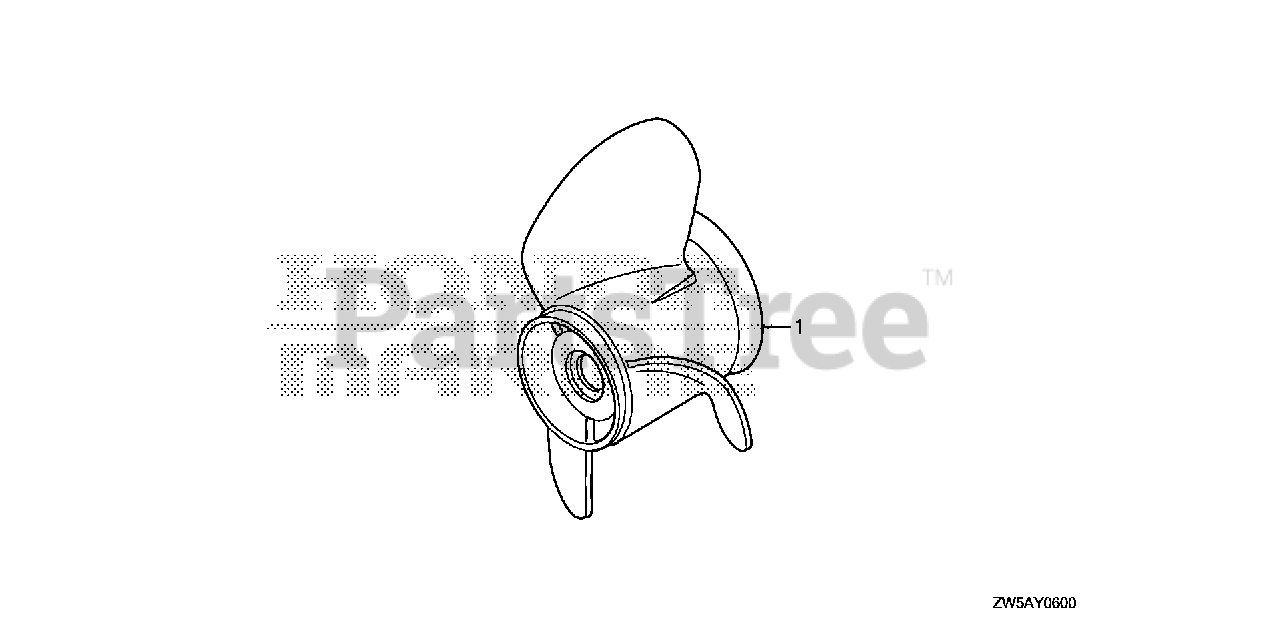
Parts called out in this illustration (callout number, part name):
1	PROPELLER, THREE-BLADE (13X19) (SUS)
1	PROPELLER, THREE-BLADE (13X21) (SUS)
1	PROPELLER, THREE-BLADE (14X11) *NH283* (AL) (STIN GRAY)
1	PROPELLER, THREE-BLADE (13-3/4X13) *NH283* (AL) (STIN GRAY)
1	PROPELLER, THREE-BLADE (13-1/4X17) *NH283* (AL) (STIN GRAY)
1	PROPELLER, THREE-BLADE (13X21) *NH283* (AL) (STIN GRAY)
1	PROPELLER, THREE-BLADE (13X19) *NH283* (AL) (STIN GRAY)
1	PROPELLER, THREE-BLADE (13-1/4X17) (SUS)
1	PROPELLER, THREE-BLADE (13-1/2X15) *NH283* (AL) (STIN GRAY)
1	PROPELLER, THREE-BLADE (13-1/4X15) (SUS/HAC)
1	PROPELLER, THREE-BLADE (13-1/4X17) (SUS/HAC)
1	PROPELLER, THREE-BLADE (13-1/4X19) (SUS/HAC)
1	PROPELLER, THREE-BLADE (13-1/4X21) (SUS/HAC)
